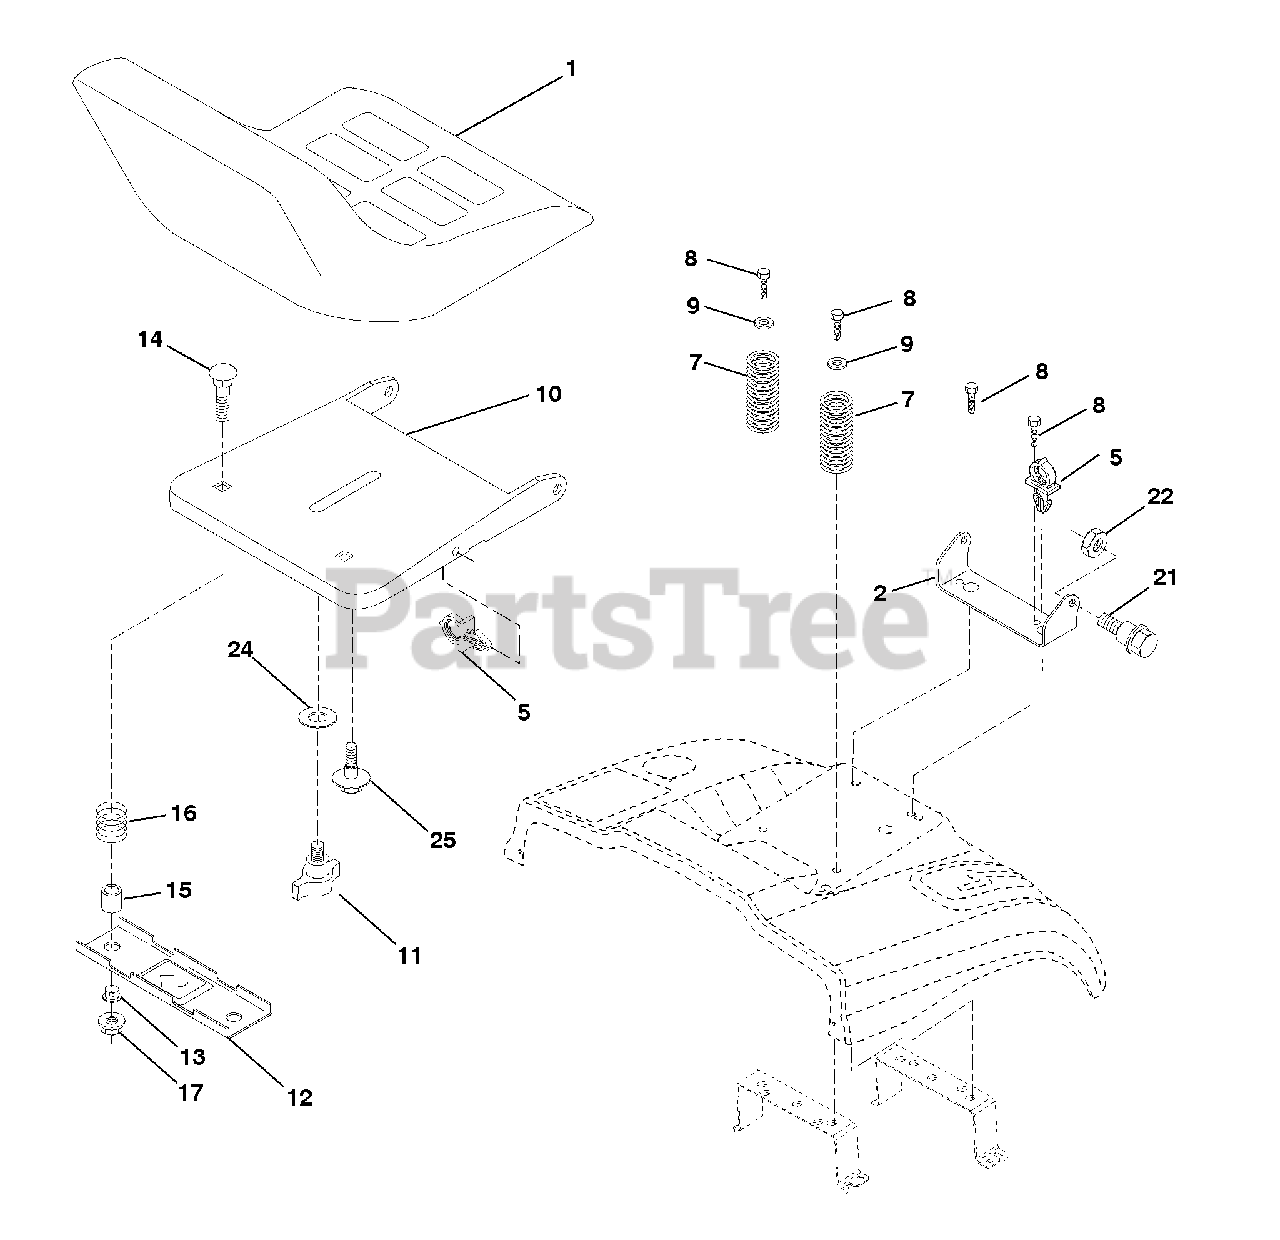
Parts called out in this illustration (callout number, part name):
1	Seat
2	Bracket Pivot Seat 8 720
5	Clip Push-In
7	Spring Seat Cprsn 2 250 Blk Zi
8	Screw 3/8-16 X 1-1/2
9	Washer 13/32 X 1 X 14 Ga.
10	Pan Seat
11	Knob Seat Adj. Wingnut
12	Bracket Mounting Switch
13	Bushing Snap Blk Nyl 50 Id
14	Bolt Rdhd Sqnk 1/4-20x1-1/2
15	Spacer Split 28x .96 Zinc
16	Spring Cprsn
17	Nut Lock 1/4 Lge Flg Gr 5 Zinc
21	Bolt Shoulder 5/16-18 Unc
22	Nut Crown Lock 5/16-18 Blk
24	Washer 17/32 X 1-3/16 X 12 Ga.
25	Bolt Shoulder 5/16-18 X 62
